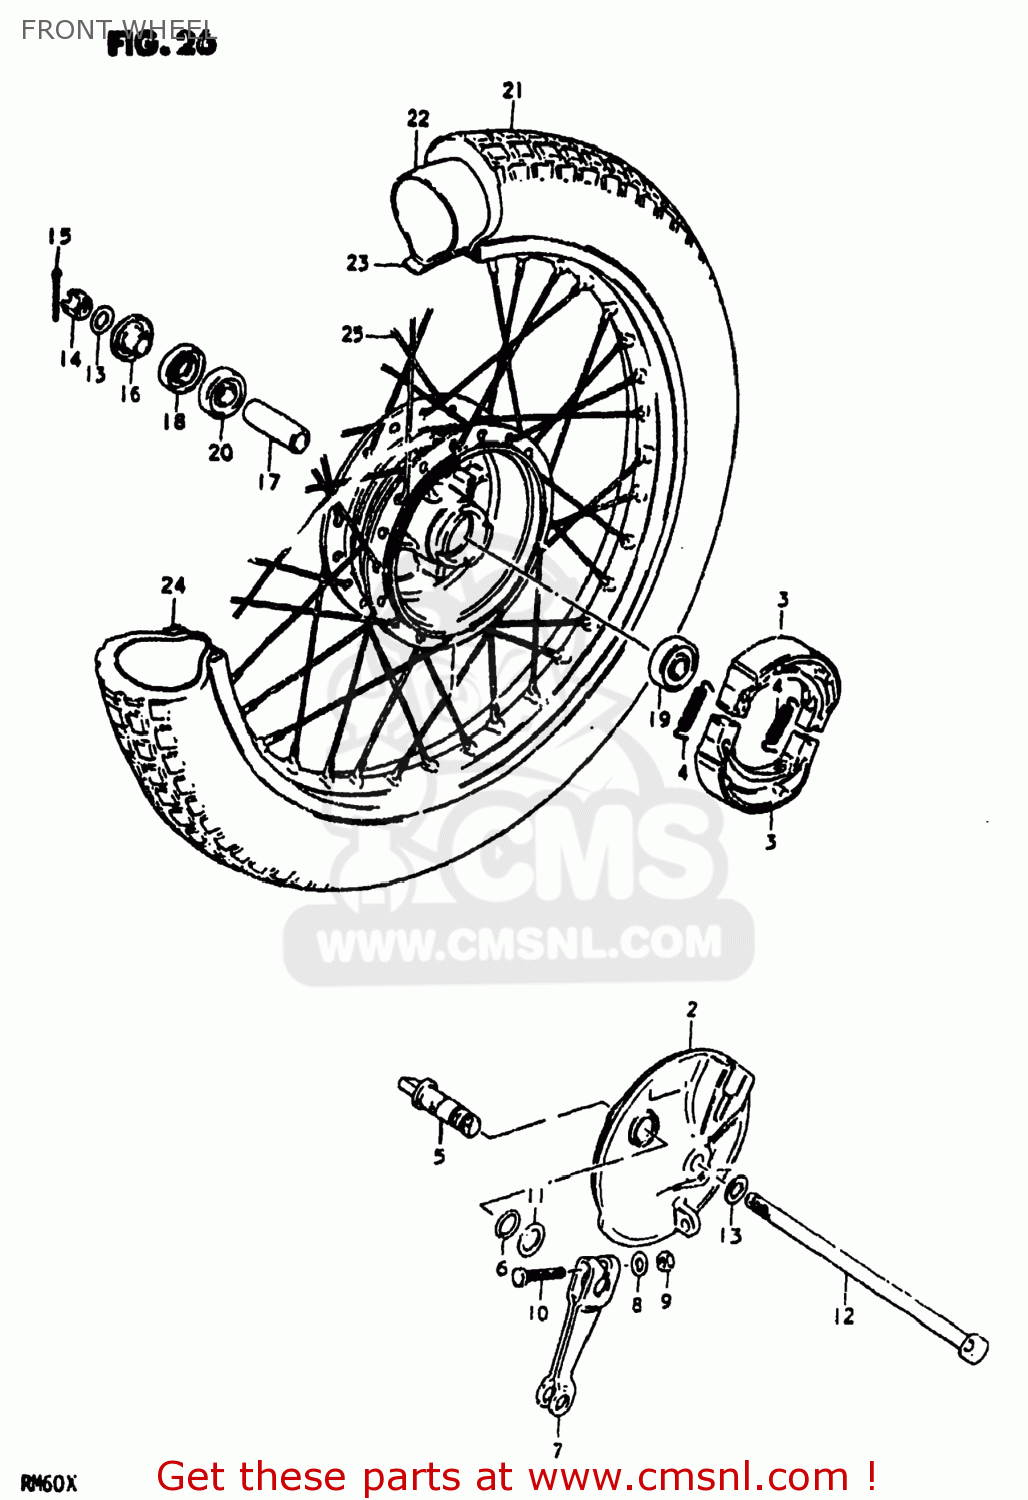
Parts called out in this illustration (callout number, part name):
1	HUB,FRONT
2	PANEL,FRONT HUB
3	SHOE,BRAKE
4	SPRING(L:34)
5	CAM,FR BRAKE
6	O RING(D:2.5,ID:11.4)
7	LEVER,FR BRAKE CAM
8	WASHER
9	NUT
10	BOLT
11	WASHER(12.5X20X1)
12	AXLE,FRONT
13	WASHER(10.5X22X2.3)
14	NUT
15	PIN 20X20
16	SPACER,FRONT AXLE,RIGHT
17	SPACER (10.2X16X51)
18	SEAL,OIL(15X31X5)
19	BEARING
20	BEARING
21	TIRE(2.25 14)
22	TUBE,INNER
23	PROTECTOR,INNER TUBE
24	RIM,FRONT WHEEL (1.40X14)
25	SPOKE SET,FRONT
